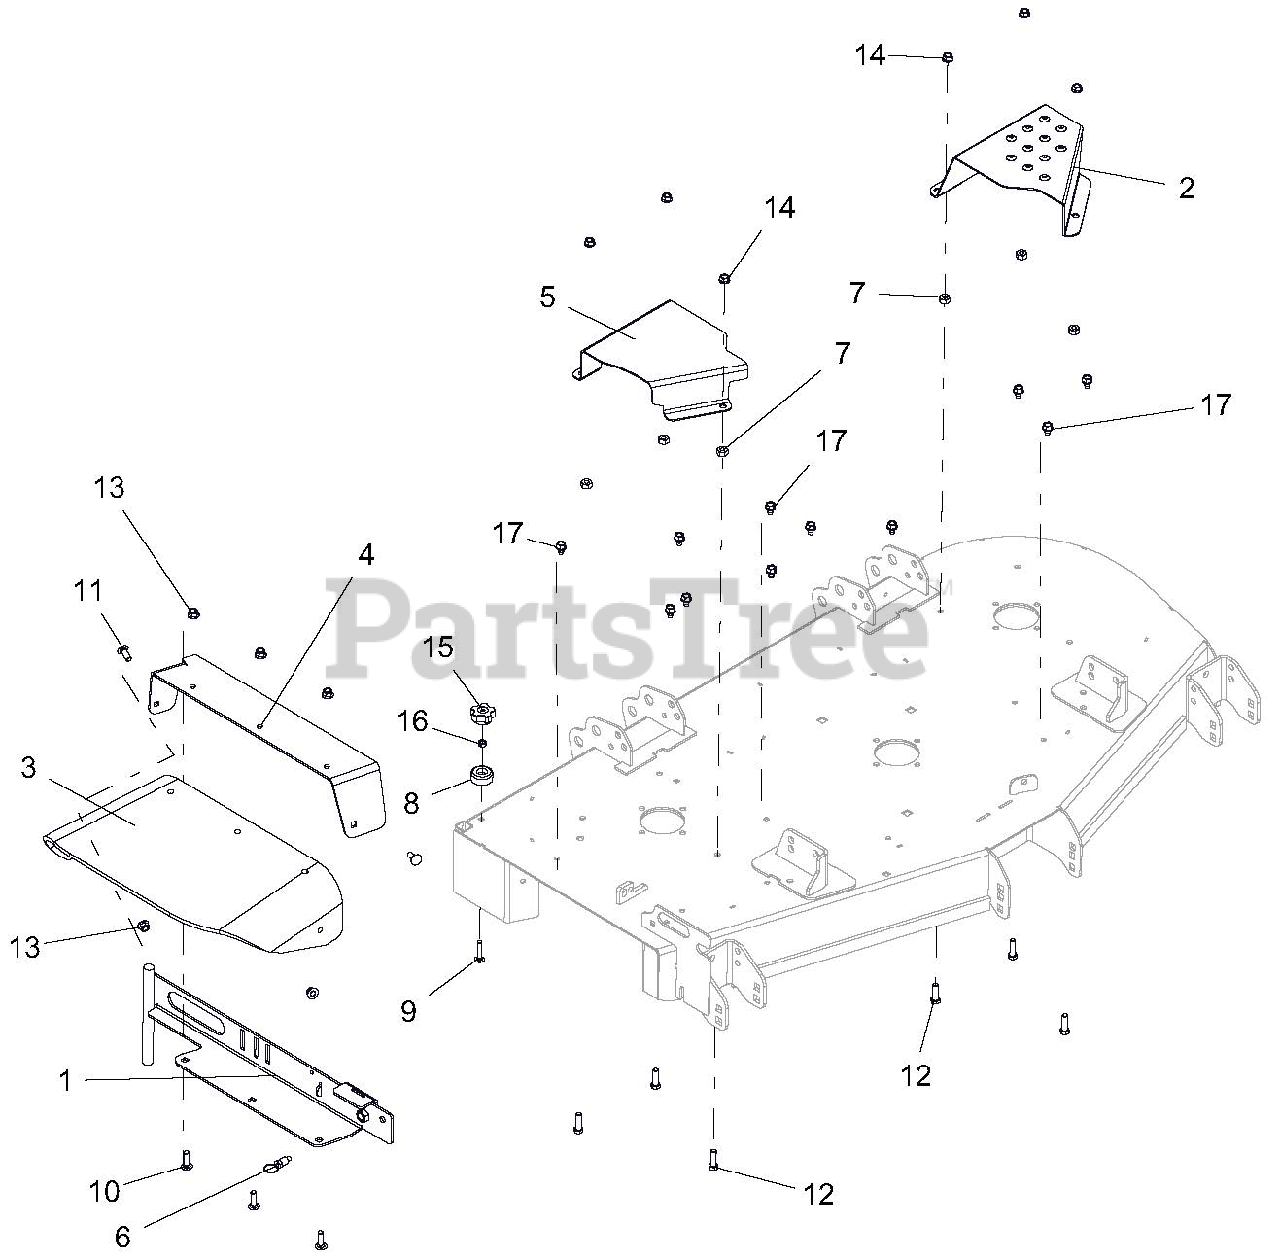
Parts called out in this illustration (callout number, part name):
1	WLDMT, 52"-60" DISCH CHUTE MTG-RED
2	GUARD, 44-52" LH DECK BELT-BLACK
3	CHUTE, RUBBER DISCHARGE
4	KIT, PT DISCH CHUTE SUPT W/SAFETY DECALS-RED
5	GUARD, 48"-52" RH DECK BELT-BLACK
6	PULL PIN,.50-13THDX.310 PLNGR
7	NUT-HEAVY HEX .38-16 YWZC
8	BUMPER, RECESSED 1.50 X .63 W/.31 HOLE
9	BLT-RDHDSQNK .31-18X1.50 G5 YWZC
10	BLT-RDHDSQNK .38-16X1.25 G5 YWZC
11	BLT-RDHDSQNK .38-16X1.00 G5 YWZC
12	BLT-HEX .38-16X1.25 GR5 YWZC
13	NUT-LK-NYL-FLG .38-16 YWZC
14	@NUT-SPNLK-FLG .375-16 YWZC
15	KNOB, CLAMPING
16	NUT-LK-CTR .31-18 YWZC
17	SCR-TAP .38-16X.50 HWH TR YWZ
